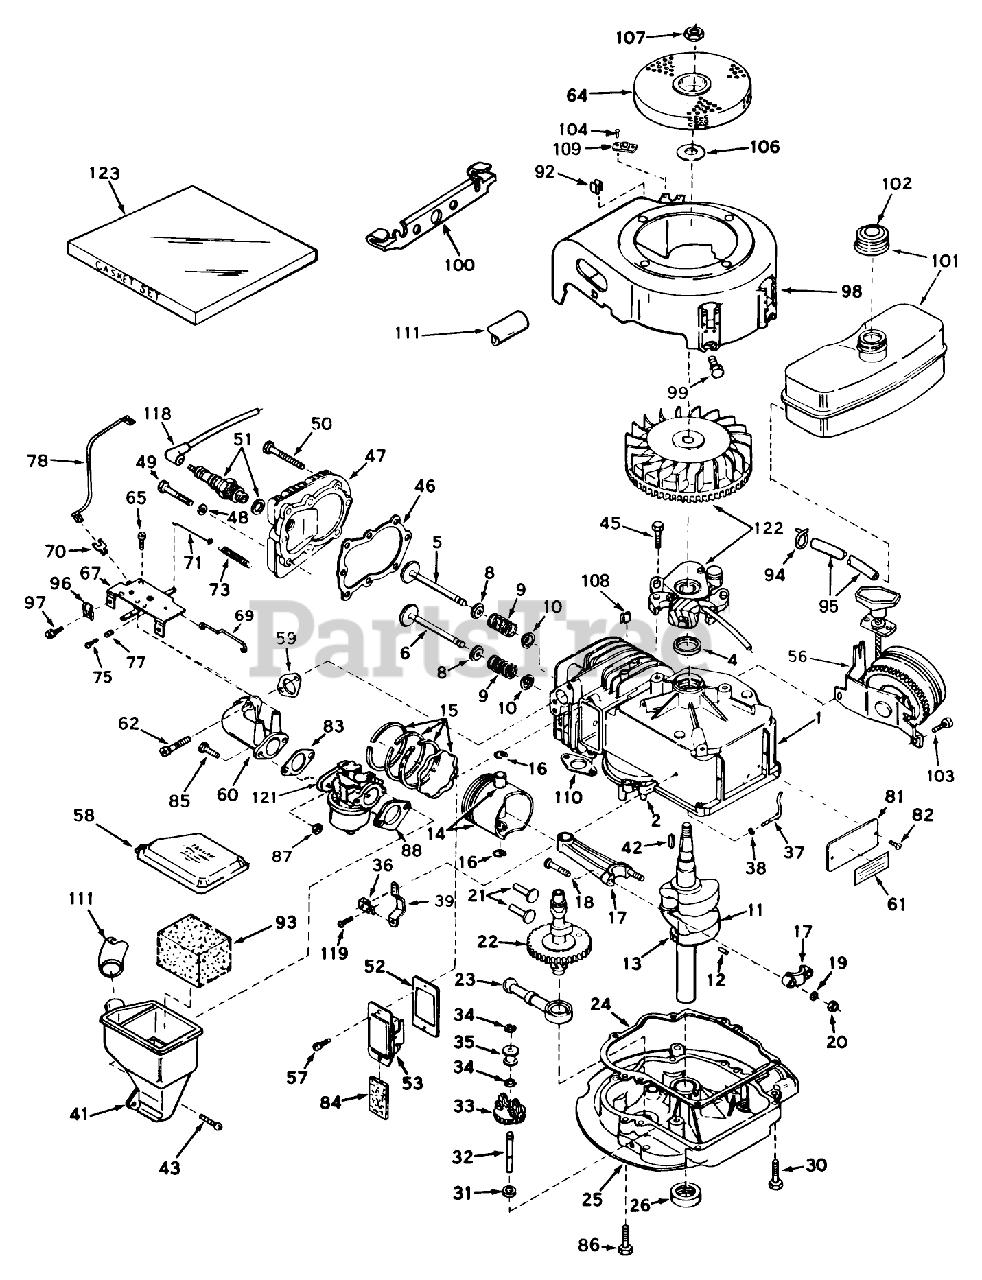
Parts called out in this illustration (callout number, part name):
1	Cylinder Assy. (Incl. Nos. 2, 4 103)
2	Pin-Dowel
4	OIL SEAL
5	Valve, Intake (Incl. Ref. #38, 39 40) (Std.)
5	Valve, Exhaust (1/32" Oversize) (Incl. Nos. 8, 9 10)
6	Valve, Exhaust (Standard) (Incl. Nos. 8, 9 10)
6	Valve, Exhaust (1/32" Oversize) (Incl. Nos. 8, 9 10)
8	Cap-Upper Valve Spring
9	Spring-Valve
10	Cap-Valve, Spring
11	Crankshaft Assy. (Incl. Ref. 12 13)(Model LAV35-40455H)
12	Pin, Groove
13	Gear, Crankshaft
14	Piston Pin Assy. (Standard) (Incl. 2 of No. 16)
14	Piston Pin Assy. (.010 Oversize) (Incl. 2 of No. 16)
14	Piston Pin Assy. (.020 Over size)(Incl. 2 of No. 16)
15	Ring Set, Piston (Std.)
15	Ring Set, Piston (.010 o.s.)
15	Ring Set, Piston (.020 o.s.)
16	Ring-Retaining, Piston Pin
17	Rod Assy., Connecting (Incl. Ref. #17)
18	Bolt, Connecting
19	Washer
20	LOCKNUT
21	Lifter-Valve
22	Camshaft (Compression Release
23	Oil Pump ASM
24	Gasket, Mounting
25	Flange Assy., Mounting (Incl. #26 32)
26	Seal Oil
30	Screw (1/4-20 x 1-1/4)
31	Washer-Flat
32	Shaft-Governor
33	Governor Gear ASM
34	Ring-Retaining
35	Spool-Governor
36	Clamp-Lever, Governor
37	Rod, Governor (Incl. No. 36)
38	Washer-Flat
39	Governor Lever
41	Body, Air Cleaner
42	Key Flywheel
43	Screw, Fil. Hd. Sems
45	Screw
46	Gasket-Cylinder Head
47	CYLINDER HEAD
48	Washer
49	Screw
50	Screw Hex Hd. Cap
51	Plug, Spark (J17LM or equiv.)
52	Gasket Breather
53	Breather Assembly (Incl. Nos. 52 84)
56	Starter, Side Mount
57	Screw
58	Cover, Air Cleaner
59	Gasket, Intake
60	Pipe, Intake
61	480B GIL SNWTHWR O/
62	Screw (1/4-20 x 1)
64	Screen, Flywheel
65	Screw (10-24 x 9/16)
67	51089 SUPP TO MANUA
69	Link Governor
70	Terminal
71	Link-Governor
73	Spring, Governor
75	Screw
77	Spring-Compression
78	Wire, Ground
81	IDENTIFICATION PLATE
82	Stud
83	Gasket
84	Element-Breather
86	Screw
87	Nut and Lock Washer (1/4-28)
88	Gasket-Air Cleaner
92	51004 GIL ROTARY TI
93	Element, Air Cleaner
94	Clamp-Line, Fuel
95	Line-Fuel (8.62)
96	Conduit
97	Screw (10-32 x 3/8)
98	Housing, Blower
99	Screw (1/4-20x19/32)
100	Bracket, Shroud
101	Tank, Fuel
102	Cap, Fuel Filler
103	Screw (1/4-20 x 1/2)
104	Rivet
106	Washer
107	Hex Nut
108	Clip-Wire
109	Bracket Assy.
110	Gasket Exhaust
111	Tube, Air Cleaner
118	Cover-Spark Plug
119	Screw
121	Carburetor (Incl. No. 83)
122	Magneto
123	Gasket Set
